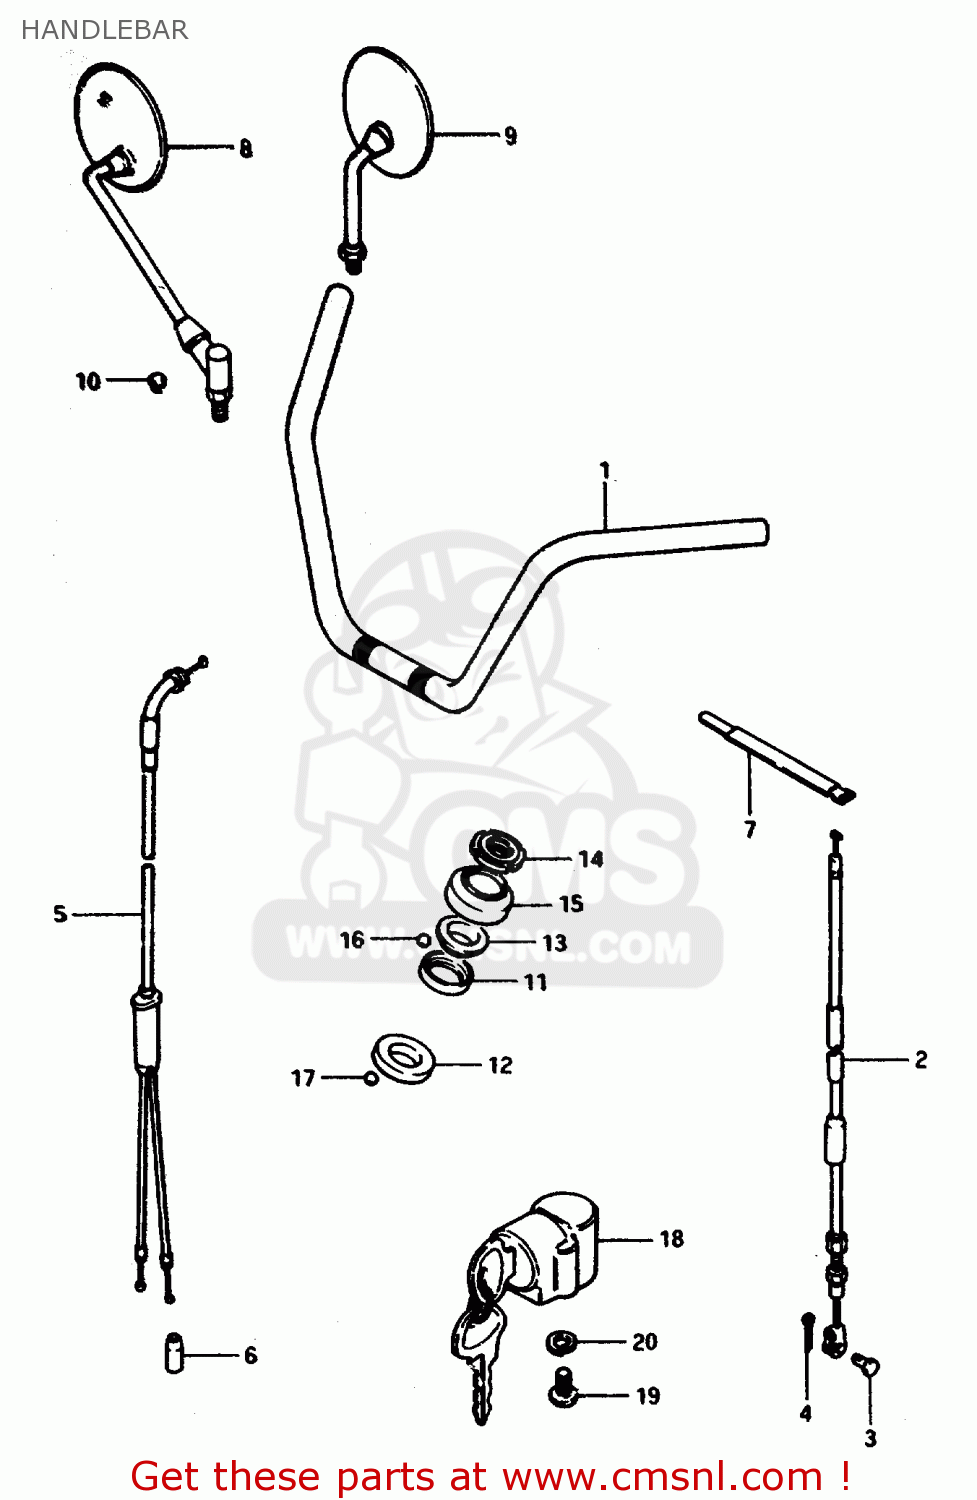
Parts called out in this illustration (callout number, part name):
1	HANDLEBAR
2	CABLE ASSY,CLUTCH
3	PIN(L:13)
4	PIN
5	CABLE, THROTTLE
6	SEAL,DUST(7X18X30)
7	CLAMP
8	MIRROR ASSY, REAR VIEW
10	CAP
11	RACE,STEERING INNER UPR
12	LACE,STEERING INNER LWR
13	RACE,STEERING OUTER UPR
14	NUT,STEERING STEM(25X44X10)
15	DUST SEAL,STEERING UPR
16	BALL
17	BALL
18	LOCK ASSY,STEERING
19	SCREW
20	LOCK WASHER
